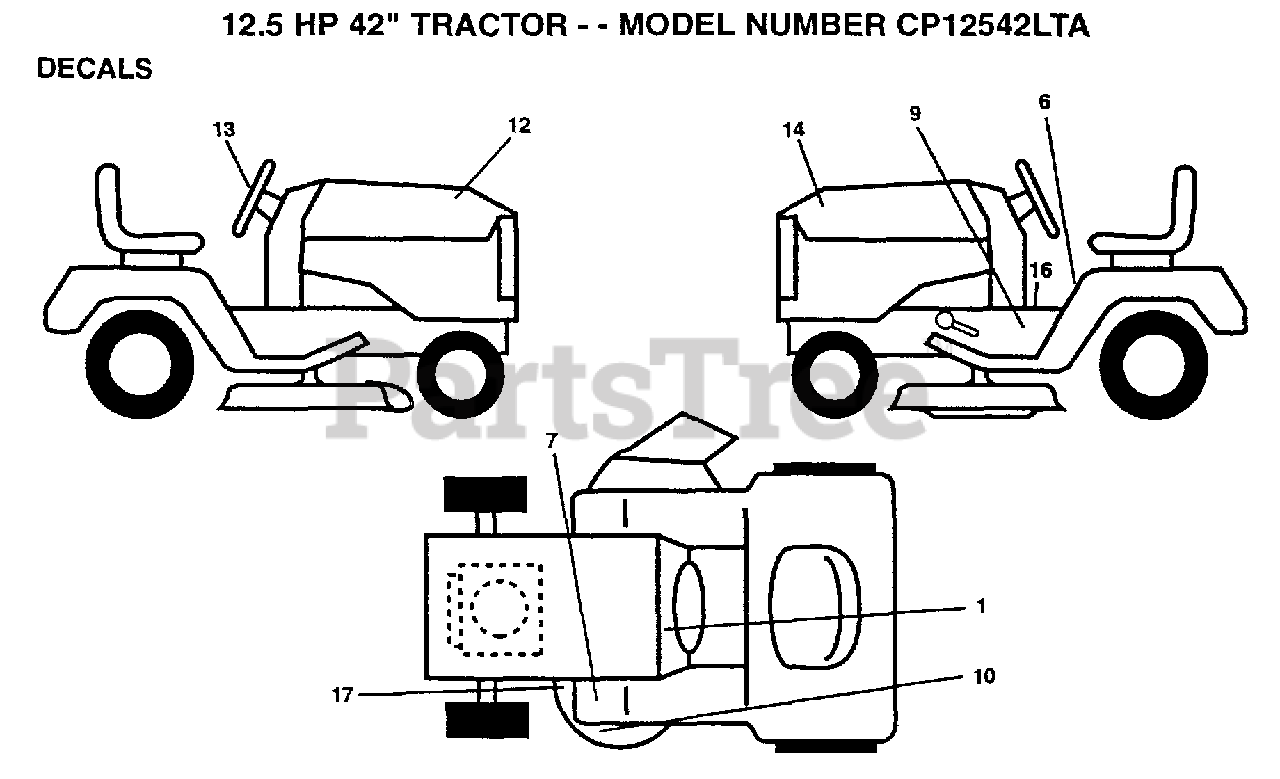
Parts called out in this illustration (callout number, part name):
1	DECAL.DASH.INST.
6	DECAL
9	CHASSIS DECAL
12	DECAL.HD.RH.CPARK
14	DECAL.HD.LH.CPARK
16	DECAL BRAK PARK
17	DECAL.V.BELT
